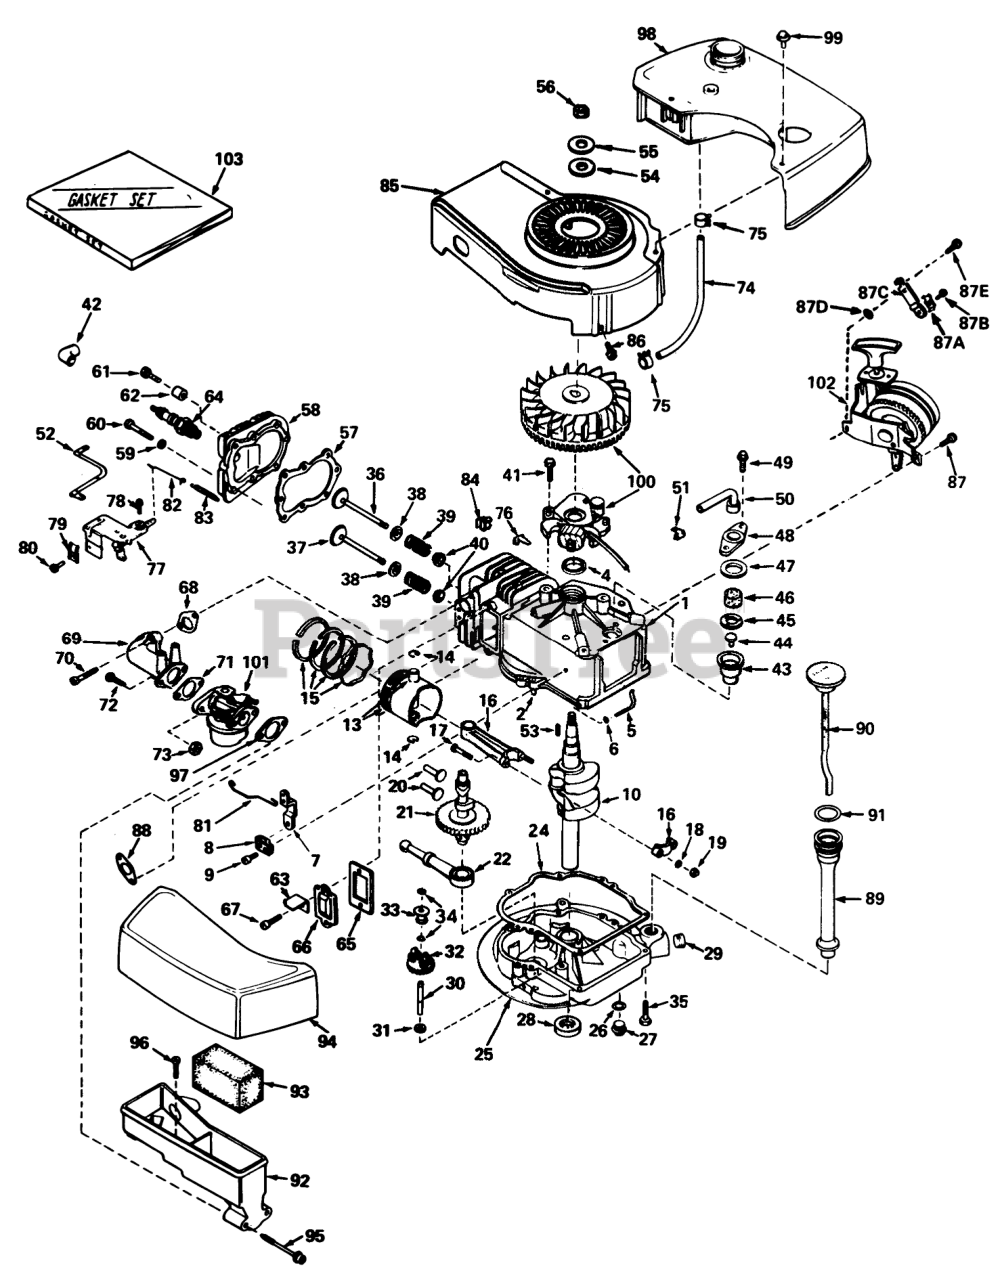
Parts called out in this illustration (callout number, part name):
1	Cylinder Assembly (Incl. Nos. 2, 4 & 87)
2	Pin-Dowel
4	OIL SEAL
5	Rod, Governor (Incl. No. 6)
6	Washer-Flat
7	Governor Lever
8	Clamp-Lever, Governor
9	Screw
10	Crankshaft (Incl. Nos. 11 & 12)
13	Piston & Pin Assembly (Incl. 2 of No. 14) (Standard)
13	Piston & Pin Assembly (Incl. 2 of No. 14) (.010 Oversize)
13	Piston & Pin Assembly (Incl. 2 of No. 14) (.020 Oversize)
14	Ring-Retaining, Piston Pin
15	Ring Set Piston (Std.)
15	Ring Set Piston (.010 Oversize)
15	Ring Set Piston (.020 Oversize)
16	Rod Assembly, Connecting (Incl. Nos. 17, 18 & 19)
17	Bolt, Connecting
19	LOCKNUT
20	Lifter-Valve
21	Camshaft (Compression Release
22	Oil Pump ASM
24	Gasket, Mounting
25	Flange Assy., Mounting (Incl. Nos. 27 thru 30)
26	Gasket-Oil Drain
27	Plug Oil Drain
28	Seal Oil
29	Plug Oil Drain
30	Shaft-Governor
31	Washer-Flat
32	Gear Assy., Governor (Incl. No. 31)
33	Spool-Governor
34	Ring-Retaining
35	Screw (1/4-20 x 1-1/4)
36	Valve, Intake (Standard) (Incl. Nos. 38, 39 & 40)
36	Valve, intake (1/32" Oversize) (Incl. Nos. 38, 39 & 40)
37	Valve, Exhaust (Standard) (Incl. Nos. 38, 39 & 40)
37	Valve, Exhaust (1/32" Oversize) (Incl. Nos. 38, 39 & 40)
38	Cap-Upper Valve Spring
39	Spring-Valve
40	Cap-Valve, Spring
42	Cover-Spark Plug
43	Body Breather Tube
44	Valve Check
45	2000A37 WIZARD ROTA
46	Element-Breather
47	Gasket-Breather
48	Cover Breather
49	Screw, Hex Hd. w/Conical
50	Tube, Breaker
51	Clip, Breather
52	Wire, Ground
53	Key Flywheel
54	Washer Flat
55	Washer-Spring
56	Hex Nut
57	63573 GIL 42 SNWTHW
58	Head Cylinder
60	Screw
61	Screw Hex Hd. Cap
63	Retainer Clip
64	Plug, Spark (J17LM or equiv.)
65	Gasket-Breather
66	Cover-Valve
68	Gasket, Intake
69	Pipe, Intake
70	Screw (1/4-20 x 1)
71	Gasket-Carburetor
72	Screw
73	Nut and Lock Washer (1/4-28)
74	Line-Fuel
75	Clamp-Line, Fuel
76	Clip-Wire
77	Control Assy., Speed
78	Screw (10-24 x 3/4)
79	Conduit
80	Screw (10-32 x 3/8)
81	Link Governor
82	Link Governor Spring
83	Spring Governor
84	51004 GIL ROTARY TI
85	Housing, Blower
86	Screw
87	Screw (1/4-20 x 1/2)
87A	Conduit
87B	Screw (10-32 x 3/8)
87C	Bracker
87E	Screw (1/4-20 X 5/8)
88	Gasket Exhaust
89	Tube, Oil Filler
90	Dipstick, Oil (Incl. No. 91)
92	Body Air Cleaner
93	Filer, Air
94	Cove, Air Cleaner
95	Screw Fil Hd.
96	Screw, Hex Hd.
97	Gasket-Air Cleaner
98	Tank Fuel
99	Screw (10-32 x 35/64)
100	Magneto
101	Carburetor (Incl. No. 71)
102	Starter
103	53024/VAR.16HP O/P
